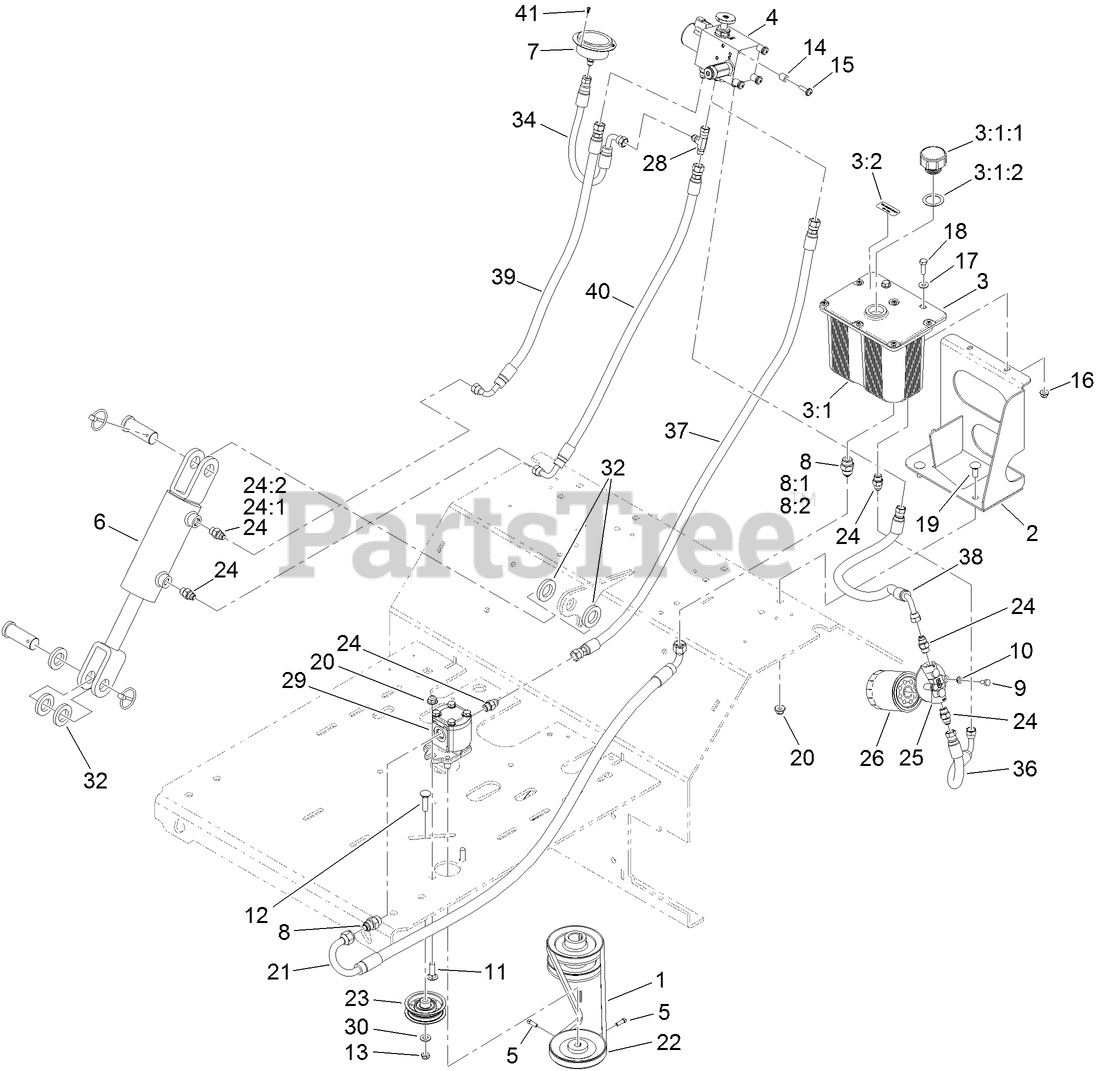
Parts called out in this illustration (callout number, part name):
1	BELT-4L SECTION
2	BRACKET-TANK, HYDRAULIC
3	RESERVOIR ASM
3:1	TANK-HYDRAULIC
3:1:1	CAP-RESERVOIR, HYD
3:1:2	GASKET-CAP
3:2	DECAL-OIL, HYD
4	VALVE-MANIFOLD
5	SCREW-SQH
6	HYD CYLINDER ASM
7	GAUGE-PRESSURE
8	FITTING-STRAIGHT
8:1	O-RING
8:2	O-Ring
9	SCREW-HH
10	WASHER-LOCK
11	BOLT-CARR
12	SCREW-CARR
13	NUT-LOCK, NI
14	SPACER
15	SCREW-PPH
16	NUT-HF, NI
17	WASHER-FLAT
18	SCREW-HH
19	BOLT-CARR
20	NUT-HF, NI
21	HOSE-HYDRAULIC
22	PULLEY
23	PULLEY-IDLER, FLAT
24	FITTING-STRAIGHT
24:1	O-Ring
24:2	O-RING
25	HEAD-FILTER
26	FILTER-OIL, HYD
28	FITTING-HYD, TEE
29	HYDRAULIC PUMP ASM
30	WASHER-FLAT
32	SPACER
34	HOSE-HYDRAULIC, HP
36	HOSE-HYDRAULIC, LP
37	HOSE-HYDRAULIC
38	HOSE-HYDRAULIC
39	HOSE-HYDRAULIC
40	HOSE-HYDRAULIC, HP
41	SCREW-TAP
